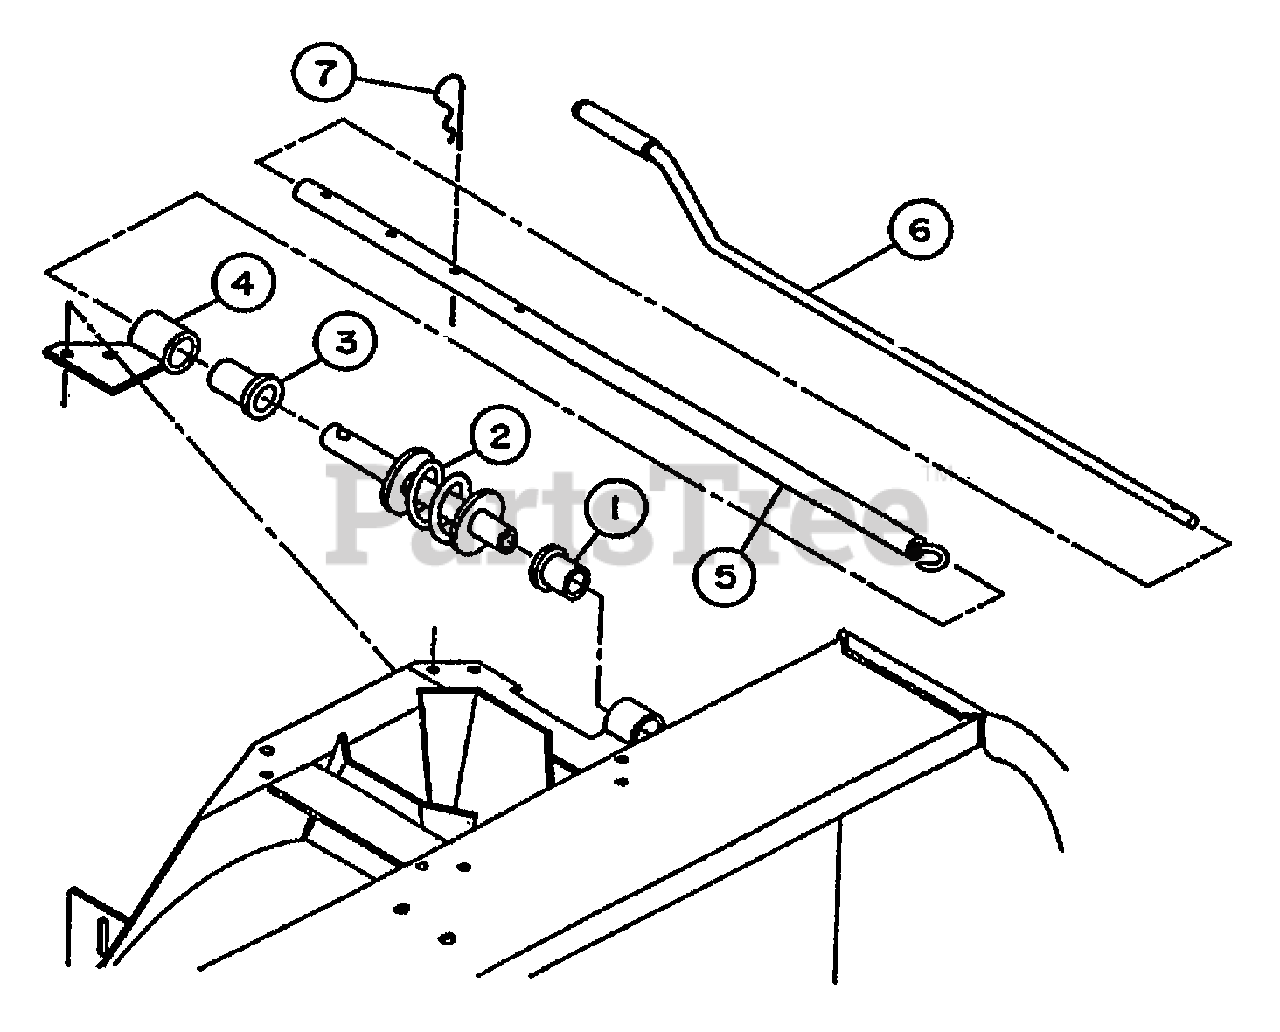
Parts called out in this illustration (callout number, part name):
1	BUSHING
2	WORM-ROTATION
3	BUSHING
5	TUBE-UPPER ROTATION
6	HANDLE
7	PIN-HITCH .149DIA
